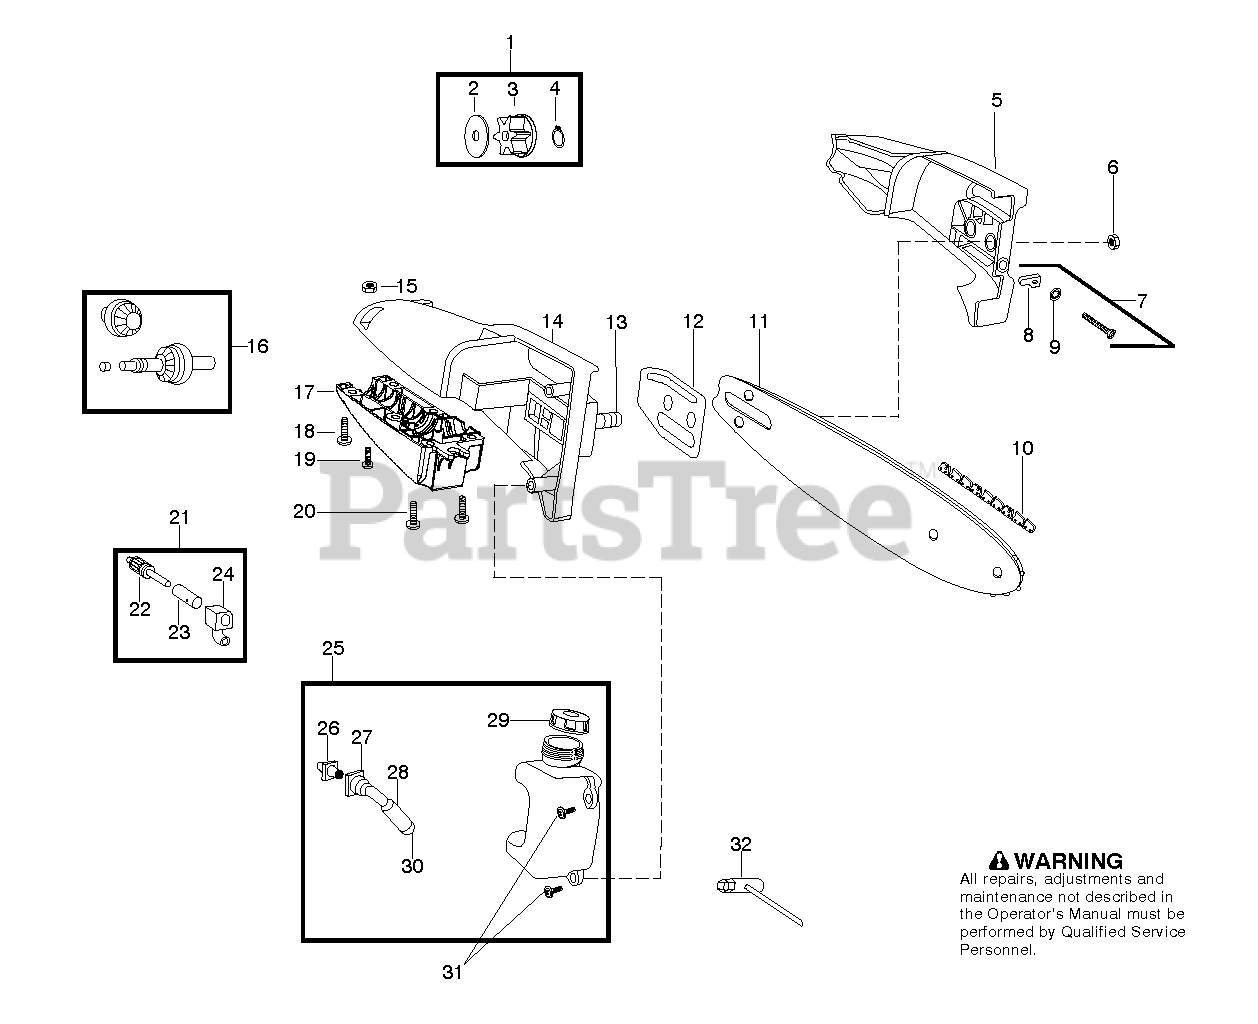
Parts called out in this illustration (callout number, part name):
1	SPROCKET
3	SPROCKET
4	RING SPROCKET RETAINER
5	BAR CLAMP ASSY
7	RETAINER
8	ADJUST PIN,BAR 36/41
9	RETAINER
10	CHAIN
12	PAD BAR PLATE
14	GEAR HOUSING UPPER
16	KIT GEAR ASSY
17	GEAR HOUSING LOWER
18	SCR 10-24 MS LDK PAN PH
19	SCREW-10-14 X 1/2 PLASTITE
20	SCREW-10-14 X 13/16 (PL
22	ASSY GEAR PLUNGER
24	OIL BLOCK ASSY
25	ASSY OIL TANK PRUNER ATTACH
26	OIL PUMP FITTING
27	LINE OIL INTAKE
28	FILTER
29	CAP OIL
30	PLUG
32	WRENCH-BAR
